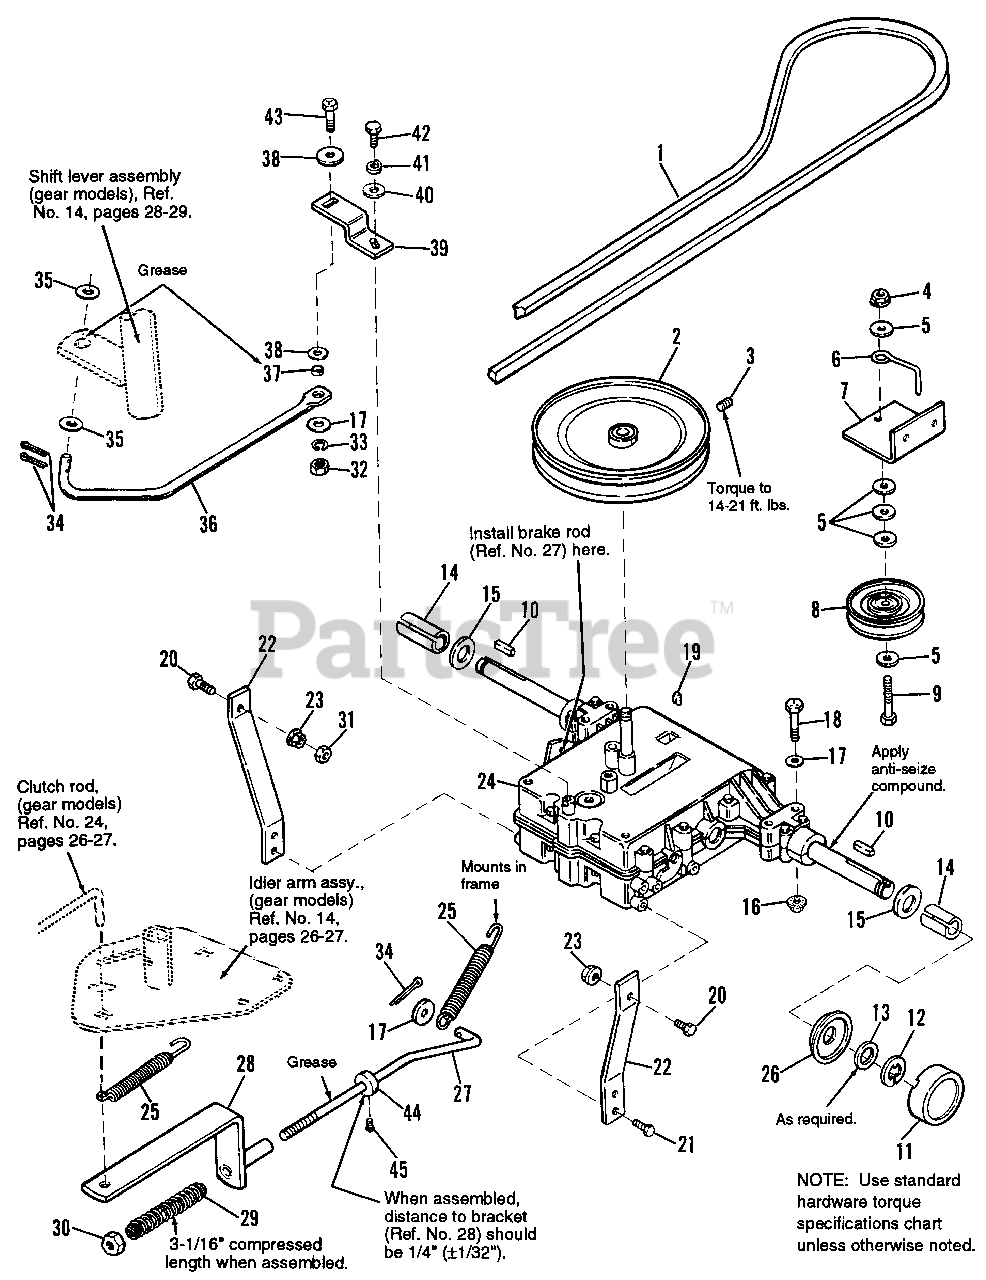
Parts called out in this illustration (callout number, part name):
2	PULLEY ASSY., Driven
3	SETSCREW, 5/16-18 x 1/2
4	NUT, Flange Whizlock, 3/8-16
5	WASHER, Plain, 3/8
6	BELT STOP
7	BRACKET, Pulley
8	PULLEY, Idler ("V")
9	CAPSCREW, Hex Hd., 3/8-16 x 1-3/4
10	KEY
13	WASHER (Rear Axle)
14	SPACER, Axle
16	NUT, Lock, Flange, 5/16-18
17	WASHER, Plain, 5/16
18	CAPSCREW, Hex, 5/16-18 x 2-1/2
19	KEY
20	SCREW, Hex, Whiz, 5/16-18 x 1-1/4
21	SCREW, Taptite, 5/16-18 x 5/8
22	SUPPORT, Transmission
23	NUT, Hex, Flange, 5/16-18
24	TRANSMISSION, 5 Speed
25	SPRING, Ext.
26	RETAINER, Hubcap
28	BRAKE ARM ASSY.
29	SPRING, Compression
30	NUT, Nylon, Lock, 5/16-18
31	NUT, Hex, Jam Lock, 5/16-18
32	NUT, Hex, Full, 5/16-18
33	LOCKWASHER, 5/16
34	COTTER PIN
35	WASHER, Plain, 1/2
36	ROD, Shift
38	WASHER
39	LEVER, Shift
40	WASHER, Plain, 1/4
41	LOCKWASHER, 1/4
42	CAPSCREW, Hex Hd., 1/4-28 x 5/8
43	CAPSCREW, Hex Hd., 5/16-18 x 1-1/4
45	SETSCREW, 1/4-20 x 3/8
